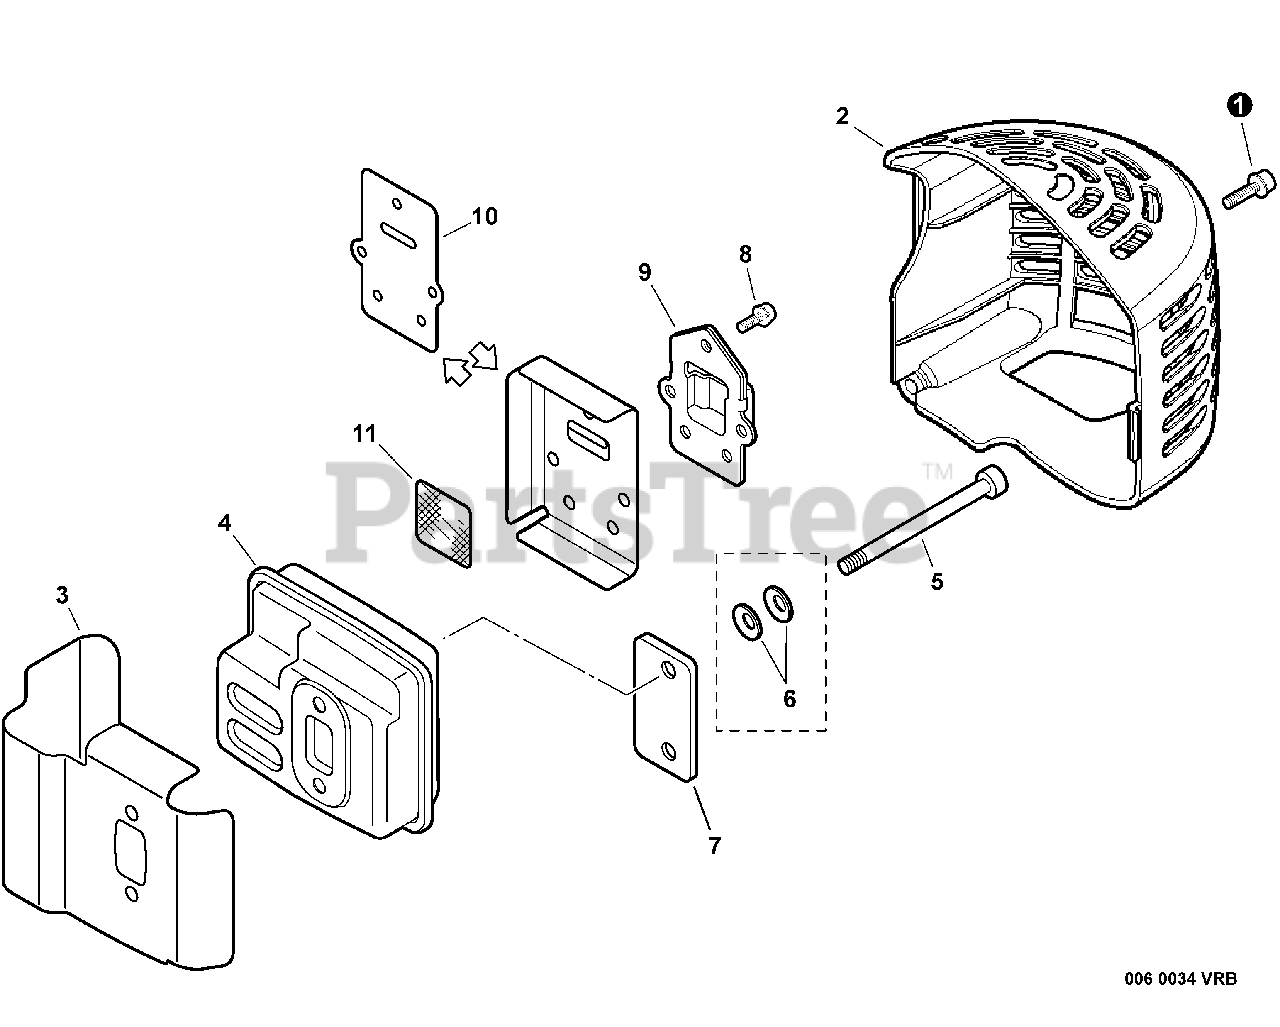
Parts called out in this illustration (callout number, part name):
1	BOLT 5×16
2	COVER, MUFFLER
3	HEAT SHIELD, EXHAUST
4	MUFFLER
5	BOLT 5×55
6	CONICAL WASHER
7	PLATE, EYE
8	SCREW 4×12
9	GUIDE, EXHAUST
10	GASKET, EXHAUST
11	SCREEN, SPARK ARRESTER
